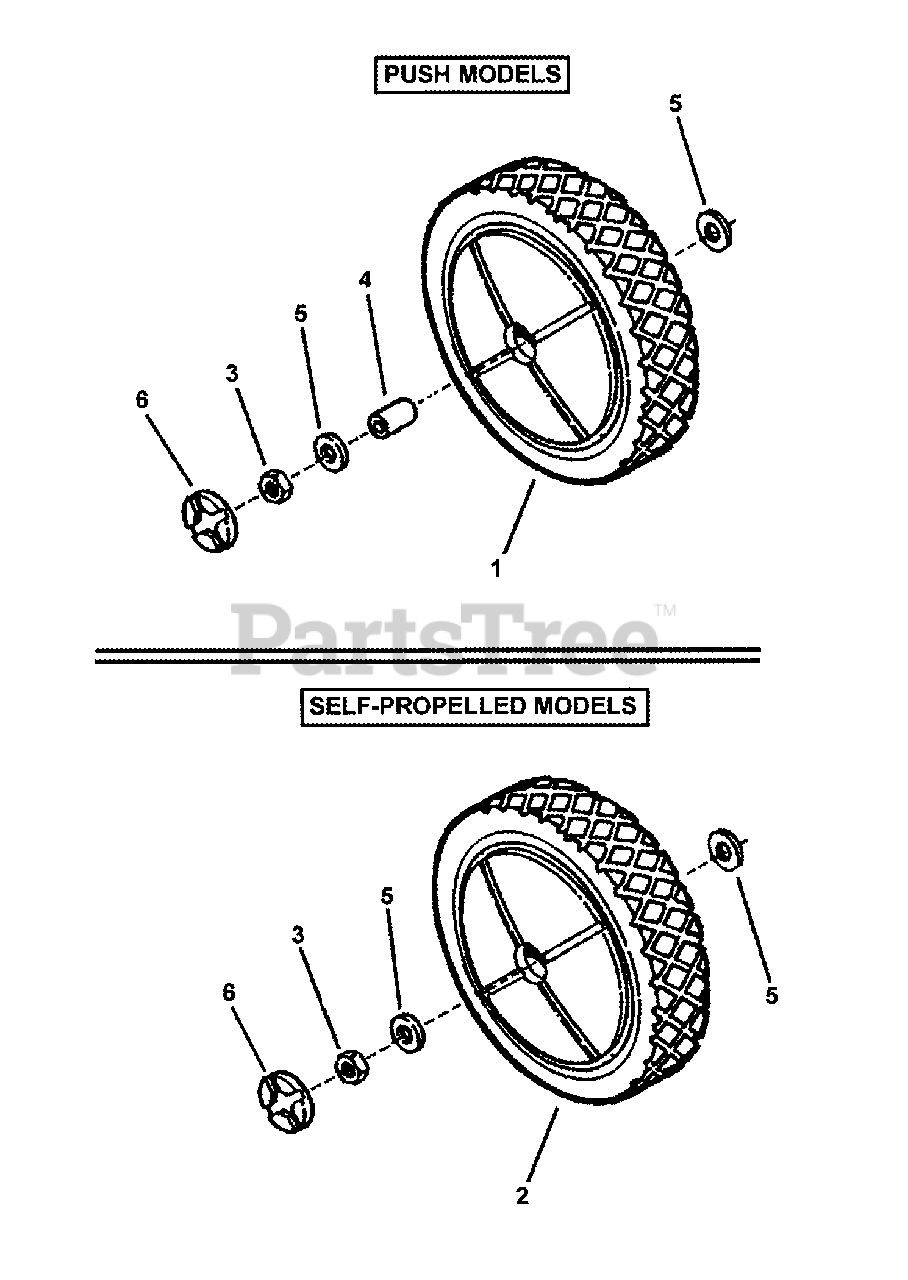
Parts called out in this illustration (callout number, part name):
1	WHEEL, 10 x 1.75" Plastic
2	WHEEL, 10 x 1.75" Plastic
3	NUT, 7/16-20 Hex Center Lock Jam
4	BUSHING, Axle
5	WASHER, 7/16" Flat
6	PLUG, Wheel
